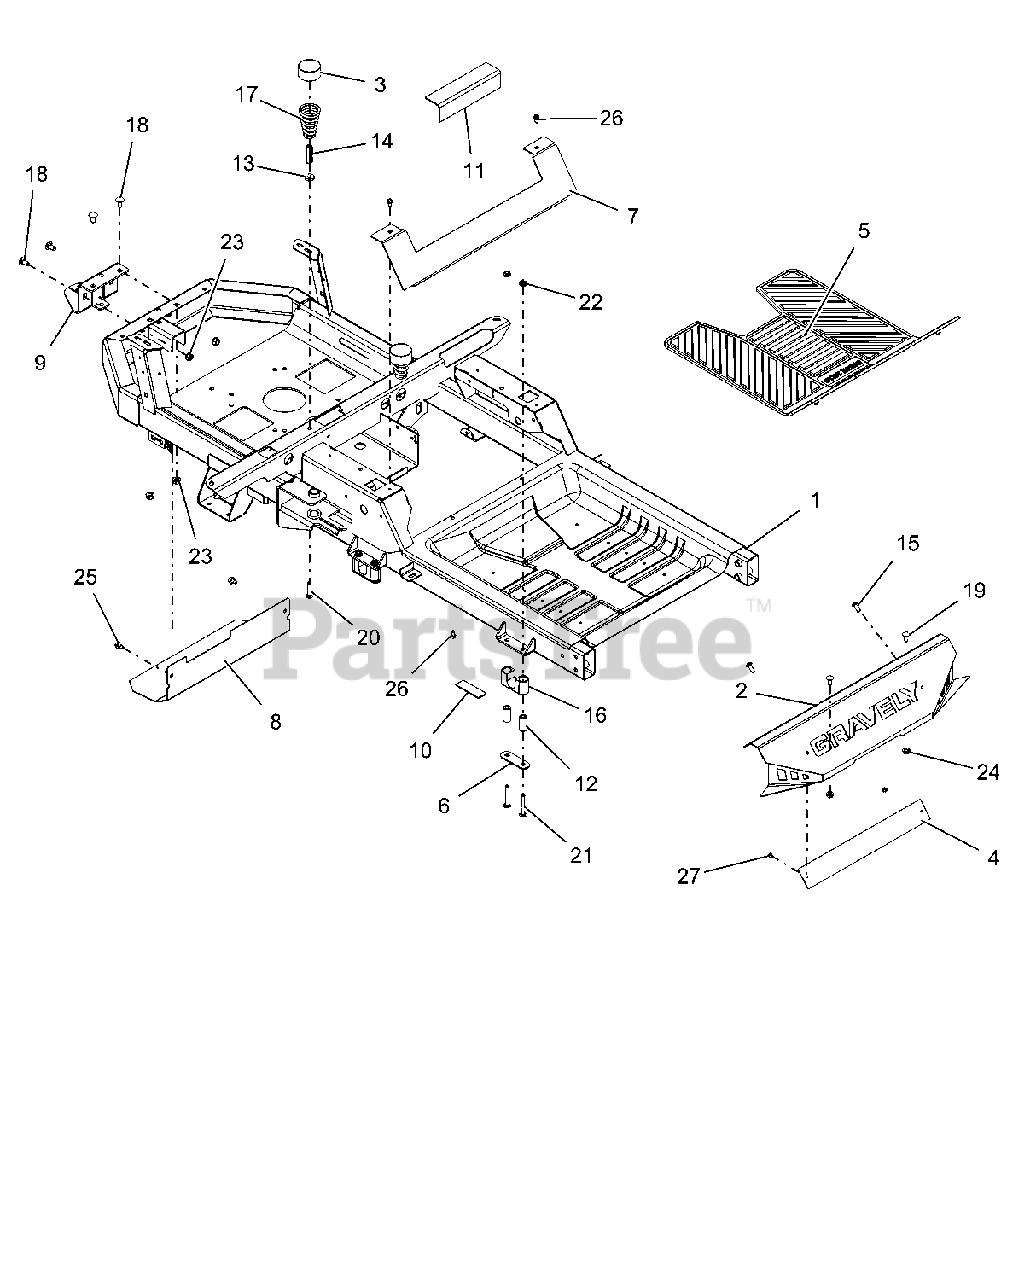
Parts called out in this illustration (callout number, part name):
1	WLDMT, FRAME IKON/ZTX
2	WLDMT, FOOTREST FRONT TRIM -GRAVELY-XL
4	PLATE, BACK XL FOOT-REST
5	FLOOR MAT-RUBBER-GRAVELY
6	PLATE, BEARING SUPPORT
7	PLATE, SEAT KICK
8	HEAT, SHIELD
9	BRKT, HITCH-RED
10	PAD, RBR 1.0"X3.0" W/ADHESIVE
11	PAD, RBR -TANK
12	SPCR, SLV .323X.448X1.403
13	WSHR-FL-STL, .328X.87X.179 YWZC
14	NUT, COUPLER 5/16-18 x 1.75
15	SCR-TAP 10-24X.25 CRSLPH TR YZ
16	BSHG, DECK LIFT PIVOT
17	SPRG, COMPRESSION
18	BLT-RDHDSQNK .38-16X.75 G5 YWZC
19	BLT-RDHDSQNK .31-18X.75 G5 YWZC
20	BLT-RDHDSQNK .31-18X1.50 G5 YWZC
21	BLT-RDHDSQSHNK .31-18X2.25 YWZC
22	NUT, LK-CTR-FLG .31-18 YWZC
23	NUT, LK-TOP-FLG .38-16 YWZC
24	NUT, LK-TOP-FLG .312-18 YWZC
25	SCR-TAP .31-18X.50 HWH TR YWZ
26	SCR-TAP .25-20X.50 HWH TR YWZ
27	RVT, POP .187x.250 AL/AL
